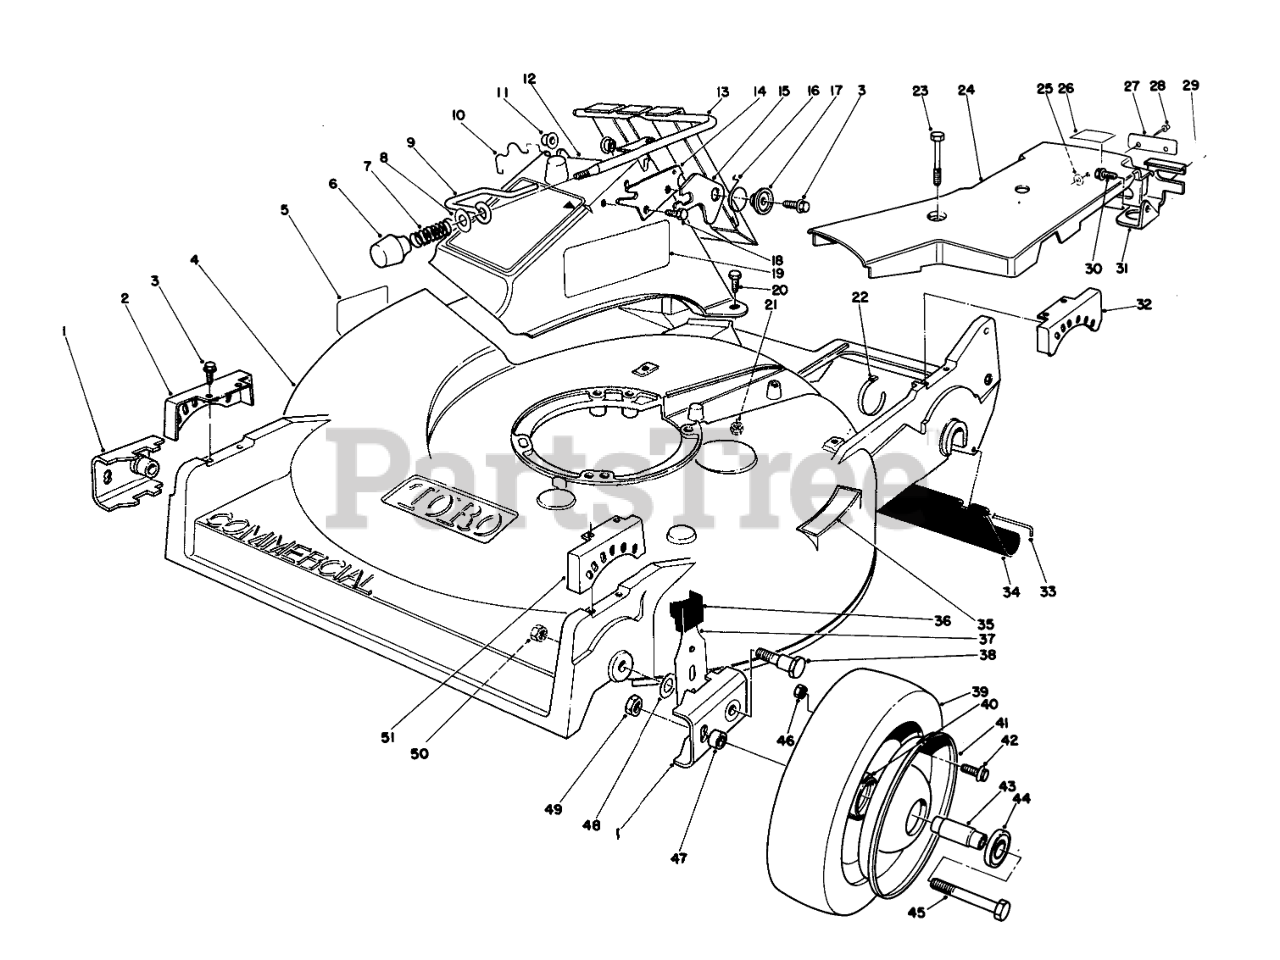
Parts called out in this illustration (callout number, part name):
1	PIVOT ARM
2	QUADRANT-FRONT, RH
3	Screw
4	Housing-Commercial (Incl. Ref. #5 & 35)
5	DECAL-DANGER
7	COMPRESSION SPRING
8	WASHER-FLAT
9	DOOR LATCH
10	DOOR RETAINER
11	BUSHING-NYLON
12	DISCHARGE CHUTE B
13	DOOR & HANDLE WA
14	DOOR LATCH PLATE
15	SAFETY LATCH
16	TORSION SPRING
17	DOOR SPACER
18	SCREW-HWH
19	DECAL SAF INST
20	SCREW-HH
21	NUT-LOCK, NI
22	TIE-CABLE
23	SCREW-HHFTF
24	Belt Cover Assembly (Incl. Ref. #25,27-28)
25	WASHER-PLAIN
26	LABEL-GREASE
27	NAMEPLATE-GRD SPEED
29	RETAINER-CABLE
30	SCREW-HWHTF
31	Bracket-Traction Adj.
32	QUADRANT-REAR, LH
33	ROD-SHIELD
34	SHIELD-TRAILING
35	STEP PAD DECAL
36	KNOB-ARM
37	SPRING ARM ASM-FRONT
38	PIVOT SCREW
40	HUB-BEARING
41	Wheel-Half
42	SCREW-HHF
43	SPACER-BEARING
44	BEARING-WHEEL
45	SCREW-HH
46	NUT-LOCK, NI
47	SPACER-WHEEL
48	WASHER-PIVOT
49	NUT-LOCK, CONE
50	NUT-LOCK, NI
51	QUADRANT-FRONT, LH
